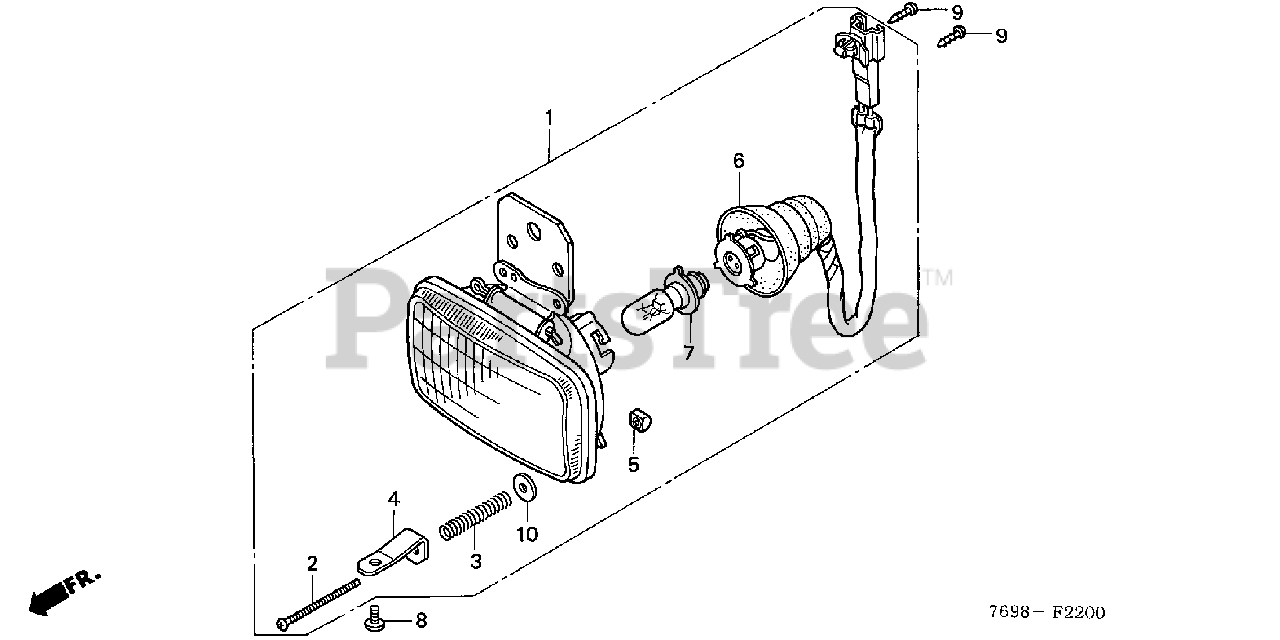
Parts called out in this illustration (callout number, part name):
1	HEADLIGHT ASSY.
2	SCREW, BEAM ADJUST
3	SPRING, HEADLIGHT BEAM ADJUSTING
4	STAY, HEADLIGHT
5	NUT, BEAM ADJ. (STANLEY)
6	SOCKET ASSY., HEADLIGHT
7	BULB (12V25/25W) (STANLEY)
8	SCREW, VISOR SETTING
9	SCREW, TAPPING (5X12)
10	WASHER, PLAIN (3MM)
